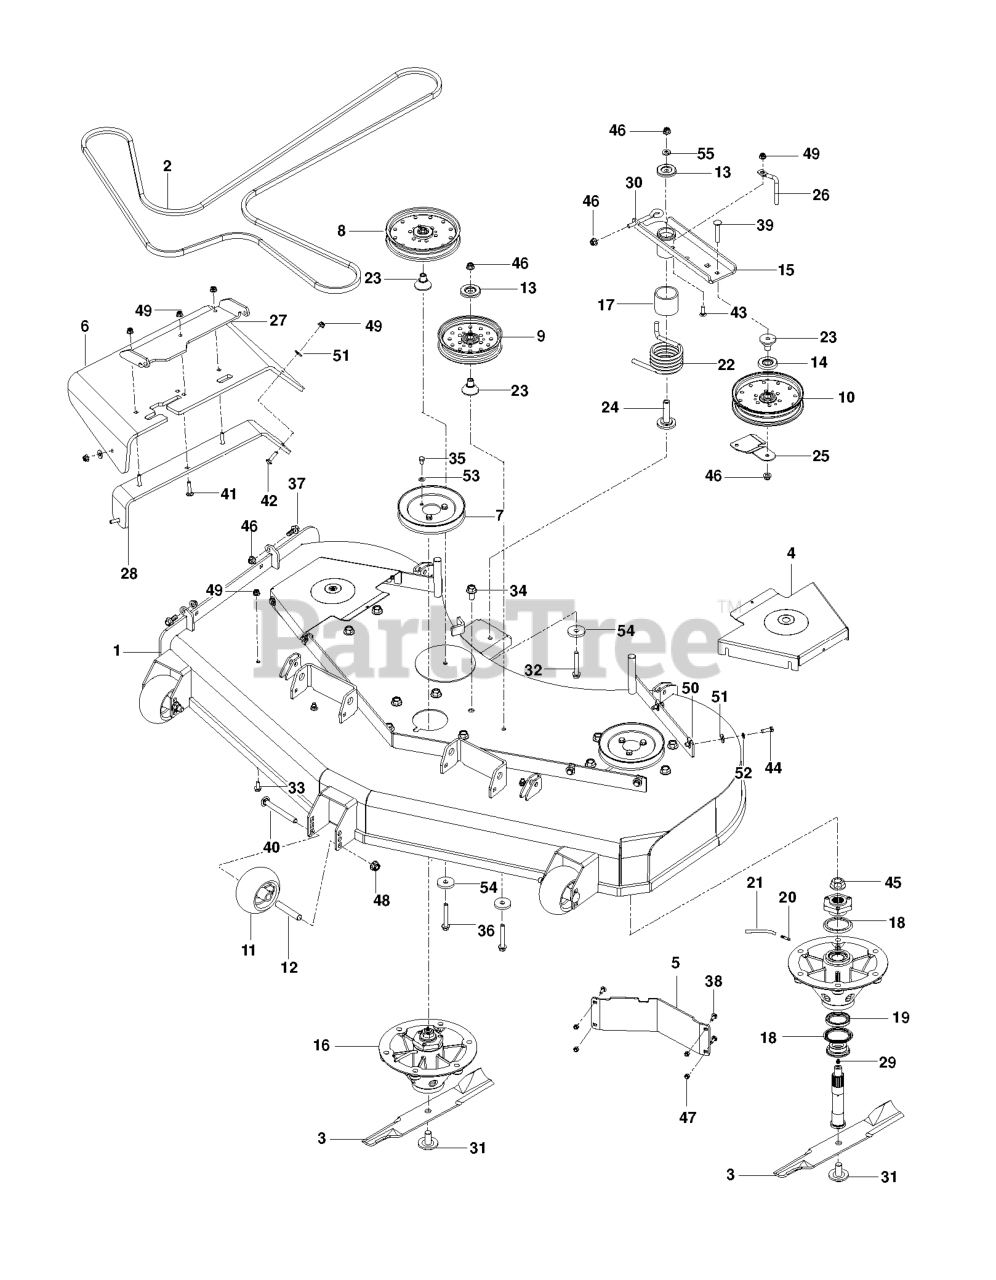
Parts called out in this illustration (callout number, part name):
1	DECK.SHELL.54".FAB.W/DECALS
2	RP_BELT, "5V", 169.75"
3	BLADE 19" HIGH LIFT (3 2)
4	SHIELD,BELT, 60" ORANGE
5	BAFFLE, DIVERTER 54"/60" LH
6	CHUTE, DISCHARGE 48-52
7	PULLEY - 6.57
8	PULLEY - 7" NARROW
9	PULLEY IDLER, 6" NARROW
10	PULLEY - IDLER 7"
11	ROLLER, GAUGE .635 BORN
12	TUBE, ROLLER AXLE
13	DUST SHIELD
14	SHIELD, DUST
15	IDLER.ARM.BLACK
16	SPINDLE ASM. 10" ALUMINUM
17	SPACER, IDLER PIVOT
18	SEAL V-RING 55MM
19	SEAL SHAFT
20	ADAPTER, FITTING, TUB
21	WHEEL.9X2.PR.SP.GY
22	SPRING, TORSION, IDLER
23	BEARING, IDLER ARM
24	BEARING, IDLER PIVOT
25	BELT.GUIDE.BLACK
26	BELT KEEPER
27	BRKT - CHUTE MTG BLACK
28	BRKT, CHUTE SUPPORT BLACK
29	ZERK
30	EYE BOLT, 3/8 X 4"
31	BLADE BOLT/WASHER
32	HCS 3/8-16 X 4-1/2 GR 8 ZD
33	HHFS 5/16-18 X 3/4
34	HHFS 1/2-13 X 1 GR5 ZD
35	HCS 5/16-18 X 1/2 GR 5 ZD
36	HHFS 3/8-16 X 2 3/4
37	HHFS 3/8-16 X 1 GRD 5 ZD
38	1/4-20X3/4 CARR BLT
39	CARRIAGE BOLT 3/8-16 X
40	RHSNB 1/2-13 X 4.75 GR5 ZD
41	RHSNB 5/16-18 X 1-1/2 GR 5 ZD
42	BOLT, CARRIAGE 5/16X1-1/4
43	RHSSNB 5/16C X 1.0
44	HCS 5/16C X 1
45	NUT FLANGE 3/4-16
46	NUT 3/8-16 HEX FLG NYLOC ZD
47	NUT.1/4-20.HEX.NYLOC.ZD
48	NUT, 1/2-13 HEX FLG NYLOC ZD
49	5/16-18 NYLOC FLANGE NUT
50	U-CLIP 5/16-18 NUT RETAINER
51	WASHER 5/16 FLAT
52	WASHER.LOCK.HVY.HLCL.SPR.5/16
53	WASH 5/16 DISC SPRING ZD
54	SPINDLE WASHER
55	WASHER, 3/8 THICK
